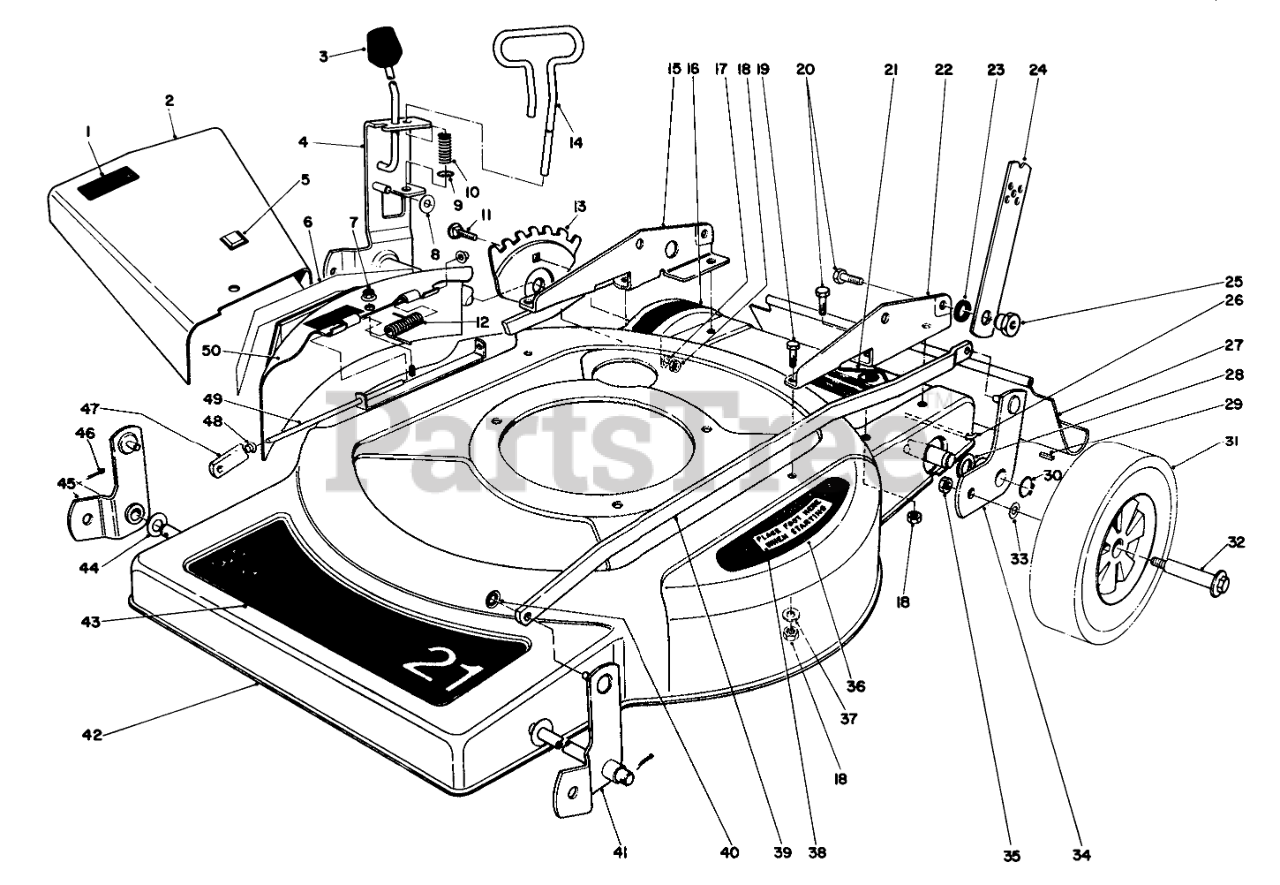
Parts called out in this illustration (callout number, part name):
1	Decal-Danger
2	Deflector-Grass (Incl. Ref. #1 & 5)
4	Pivot Arm
5	Bumper
6	Decal-Cover
8	WASHER-FLAT
9	E-RING
10	SPRING-COMPRESSION
11	Carriage Bolt
12	Spring
13	HOC ADJUSTMENT PLT
14	STOP ROD
15	Bracket Handle R.H.
16	Decal Height of Cut
17	WASHER-PLAIN
18	NUT-LOCK, CONE
19	SCREW-HH
20	SCREW-HH
21	DECAL-DANGER
22	Bracket-Handle R.H.
23	HANDLE LATCH SPACER
24	HANDLE LATCH
25	HANDLE PIVOT NUT
26	SHIELD ROD
27	SHIELD - TRAILING
28	WASHER-FLAT
29	KEY-SQUARE
30	RING-RETAINING
31	WHEEL TIRE ASM 8 IN
32	BOLT-WHEEL
33	WASHER
34	Pivot Arm
35	Nut
36	PAD STEP
37	WASHER-FLAT
38	Decal Step Pad
39	Spanner Link L.H.
40	NUT-PUSH
41	LH FRT PIVOT ARM WA
42	Housing (Incl. Ref. #16, 21, 36 & 38)
43	Decal Deck
44	WASHER
45	Pivot Arm
46	PIN-COTTER
47	Spanner Link R.H.
48	PUSHNUT-CAP, WASHER
49	DEFLECTOR PIVOT ROD
50	Mulcher Cover (Incl. Ref. #1)
